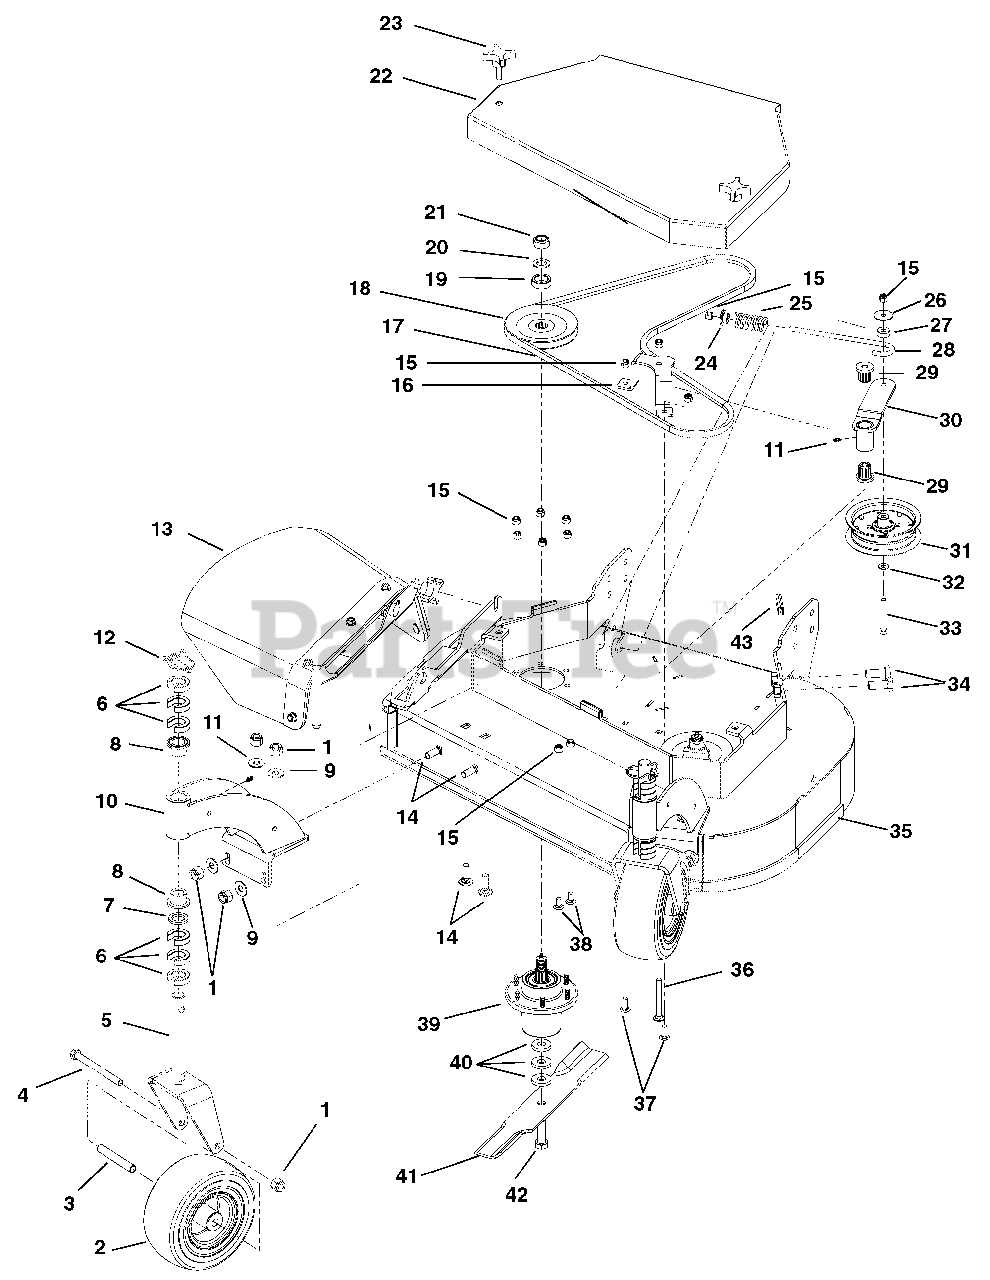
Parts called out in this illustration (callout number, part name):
1	Locknut, .50-13 Nyloc
2	Assembly, Wheel and Tire 9 x 3.5
3	Tube, Caster Axle
4	Bolt, .50-13 x 5.50 Hex Grade 5
5	Weldment, Caster Yoke w/Gravely Paint
6	C-Spacer, 1.00 x 1.77 x .500
7	Bushing, 1.03 x 1.50 x .179
8	Bearing, Flange 1.00 x 1.25 x 1.00
9	Washer, .438 Regular Flat
10	Weldment, Strut Front FXWLK w/Gravely Paint
11	Fitting, .25-28 Straight Grease Zerk
12	Pin, LNC .438 x 2.00
13	Discharge Shield Assembly
14	Bolt, Round Head Square Neck .50-13 x 1.50 Grade 5
15	Locknut, .38-16 Nyloc
16	Bracket, Idler
17	Belt, HB 80.3 Elbow AMD OHR
18	Pulley, V-Belt Narrow Spline
19	Spacer, Spindle Top-Pulley 1.500 x 1.000 x .510
20	Washer, .75 x 1.313 x .113
21	Locknut, .75-16 Crown
22	Weldment, Belt Shield 36" GRWK
23	Knob, .375 x 1.25-4 Prong
24	Keeper, Spring
25	Spring, COM 1.22 x .162 x 2.50
26	Washer, Flat .375 x 1.50 x .063
27	Bushing, .380 x 1.00 x .410
28	J-Bolt, .375-16 x 7.88
29	Bearing, Flange M10 x M25 x M27 Fluted
30	Weldment, Idler Arm w/Offset
31	Pulley, Flat 5.0 x .38 w/BRG
32	Washer, .406 x .813 x .065 Flat
33	Bolt, .38-16 x 2.75 Hex Grade 5
34	Bolt, Hex .625-11 x 1.50 Grade 8
35	36" Gravely Gear Deck with Decals
36	Bolt, .375-16 x 3.50 Round Head Square Neck Grade 5
37	Bolt, .375-16 x 1.00 Round Head Square Neck Grade 5
38	Bolt, Round Head Square Neck .38-16 x .75
39	Assembly, Spindle Housing
40	Washer, Blade
41	Blade, 18.000 x .80 Lift
42	Bolt, .625-11 x 2.00 Hex 8
43	Trim, 1/4" Trim-LOK
